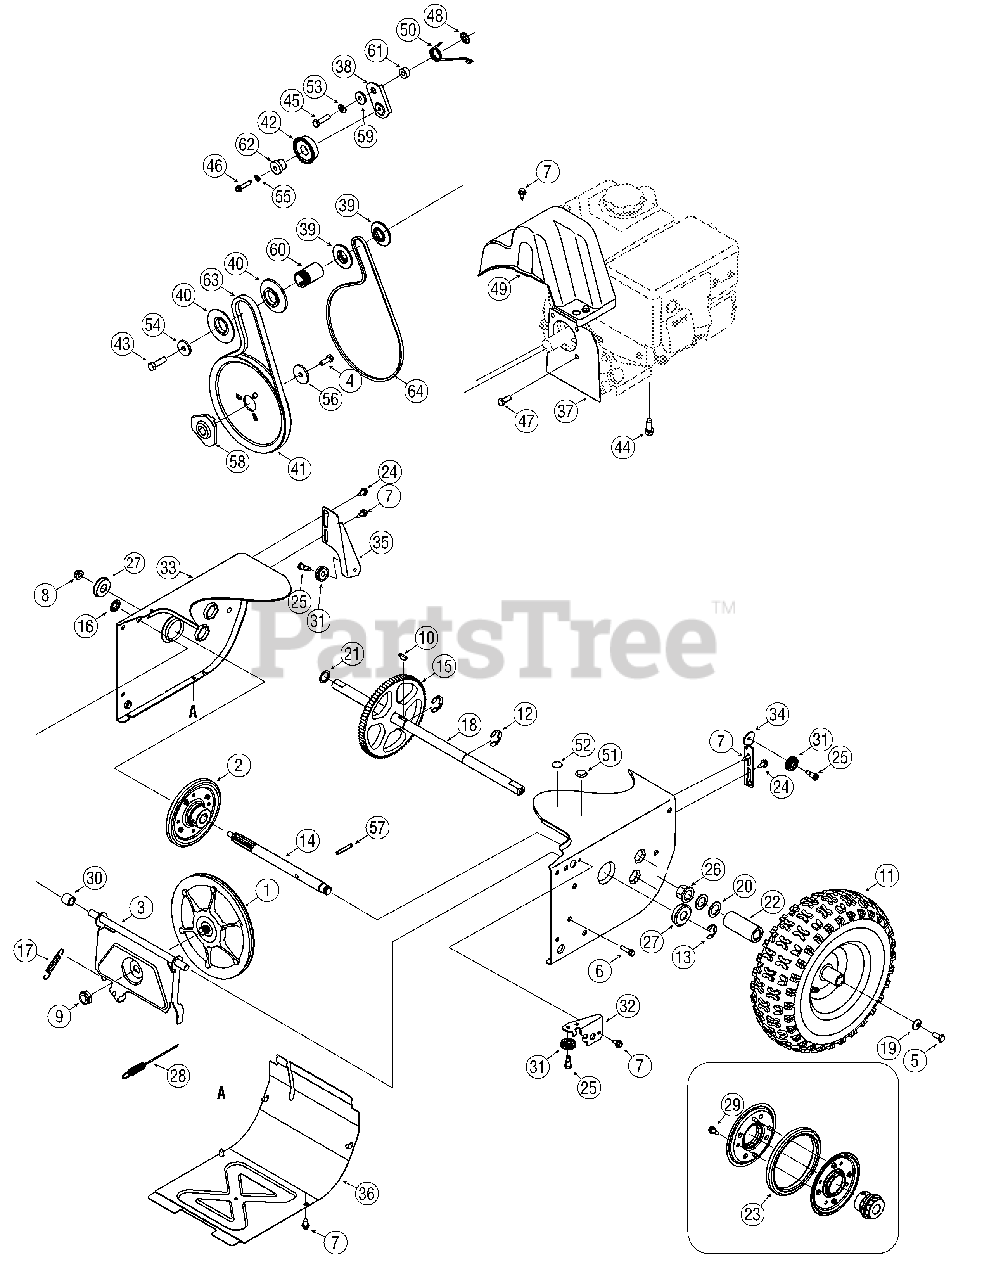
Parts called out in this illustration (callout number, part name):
1	Disc Assembly, Friction Wheel
2	Friction Wheel Assembly
3	Friction Wheel Support Bracket
4	Screw, 5/16-24 x .875
5	Hex Head Screw, 5/16-24 x .750
6	Taptite Screw, 1/4-20 x 1.000
7	Taptite Screw, 1/4-20 x .625
8	Flange Lock Nut, 3/8-16
9	Flange Nut, 5/8-18
10	Hi-pro Key, 3/16 x 3/4 Dia.
11	Snow Hog Wheel, 13 x 4 x 6
12	Retaining E-Ring, .875 Dia.
13	E-Ring, .750 Dia.
14	Shaft, Single-Speed
15	Gear, 80-Tooth
16	Speed Nut, .500
17	Extension Spring
18	Axle, .75 x 20
19	Bell Washer, .340 x .872 x .060
20	Flat Washer, .793 x 1.24 x .060
21	Flat Washer, .75 x 1.00 x .060
22	Spacer, 1.25 x .75 x 2.0
23	Friction Wheel Rubber
24	Shoulder Screw, .368 x .113, 1/4-20
25	Shoulder Screw, 1/4-28, .340 x .355
26	Hex Flange Bearing
27	Ball Bearing, 17 x 40 x 12
28	Wheel Clutch Cable, 44.95"
29	Screw, 1/4-14 x .625
30	Spacer, .508 ID x .75 OD x .68
31	Cable Roller
32	Auger Cable Front Guide Bracket
33	Frame
34	Auger Cable Guide Bracket
35	Drive Cable Guide Bracket
36	Frame Cover
37	Cover Plate, Standard
38	Wheel Drive Idler Bracket
39	Pulley Half, 3/8 x 1.716 OD
40	Pulley Half, 2.600 OD
41	Auger Drive Pulley, 8.1 x .5
42	Idler Pulley Assembly
43	Hex Screw, 3/8-24 x 1.25
44	Sems Screw, 3/8-16 x 1.00
45	Hex Screw, 5/16-24 x 1.25
46	Hex Screw, 1/4-20 x 1.25
47	Shoulder Screw, 5/16-24 x .5
48	Push-on Nut, .25 Dia.
49	Belt Cover
50	Torsion Spring, .850 ID x .333
51	Plug, 3/8 ID
52	Plug, 1/2 ID
53	Lock Washer, 5/16
54	Flat Washer, .406 x 1.25 x .157
55	Washer, Lock, 1/4
56	Flat Washer, .34 x 1.50 x .150
57	Pin, Spirol, 2.5"
58	Adapter Pulley, .75 Dia.
59	Shoulder Spacer, .3175 x .5 x .0975
60	Spacer, .875 ID x 1.185 OD
61	Spacer, .340 x .750 x .330
62	Shoulder Spacer, .260 x .785 x .538
63	Auger Drive Belt
64	Wheel Drive Belt
